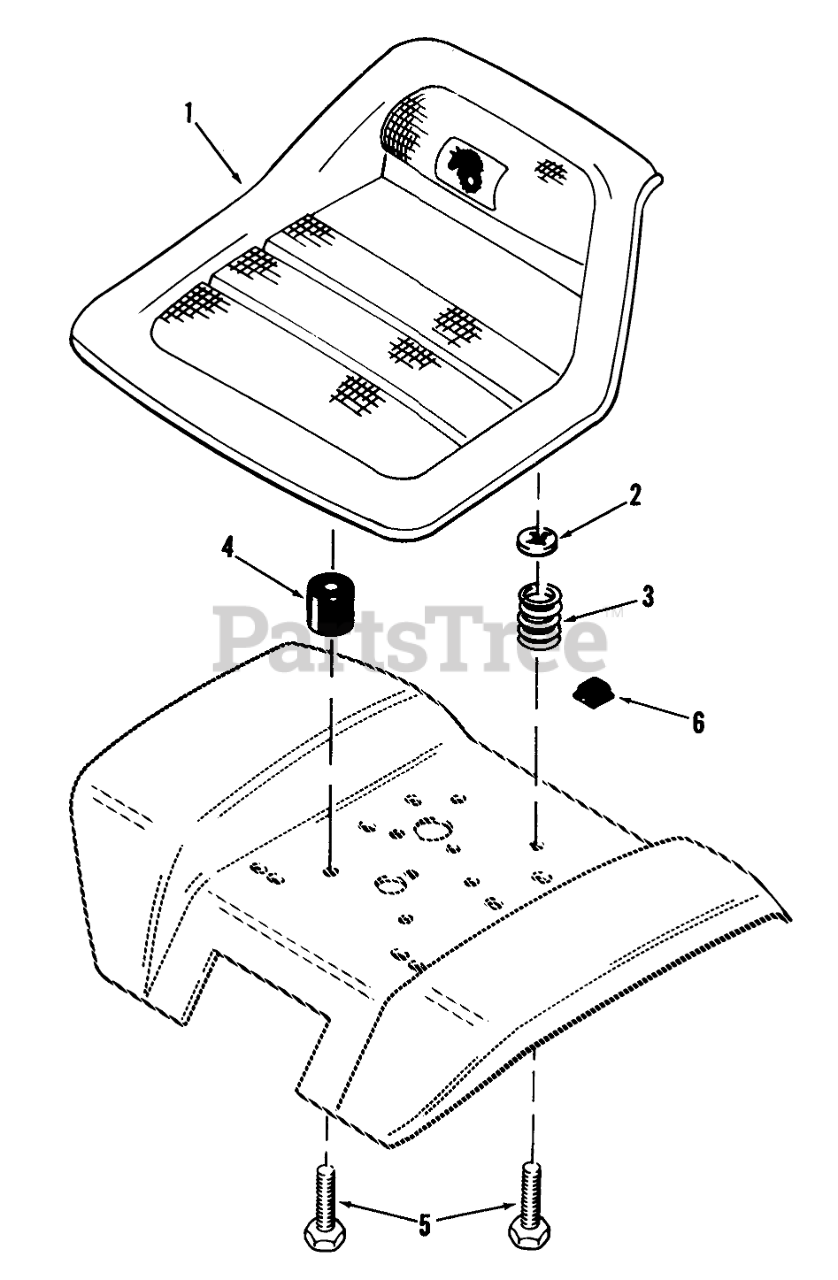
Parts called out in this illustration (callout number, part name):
1	Seat
2	NUT-PUSH
3	SPRING
4	GROMMET-RUBBER
5	SPECIAL BOLT
5	HHCS
6	BUMPER
